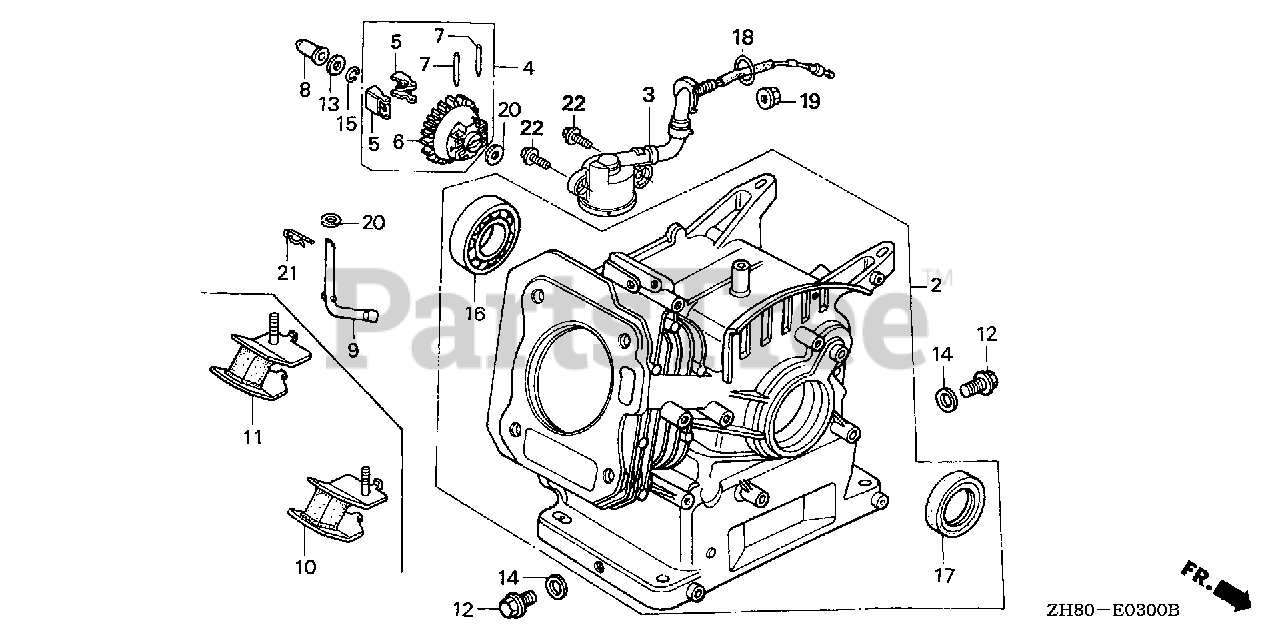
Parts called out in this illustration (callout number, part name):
2	CYLINDER ASSY.
4	GOVERNOR ASSY.
5	WEIGHT, GOVERNOR
6	HOLDER, GOVERNOR WEIGHT
7	PIN, GOVERNOR WEIGHT
8	SLIDER, GOVERNOR
9	SHAFT, GOVERNOR ARM
12	BOLT, DRAIN PLUG
13	WASHER, THRUST (6MM)
14	WASHER, DRAIN PLUG (10.2MM)
15	CLIP, GOVERNOR HOLDER
16	BEARING, RADIAL BALL (6205TMB) (NTN)
17	OIL SEAL (25X41X6)
20	WASHER, PLAIN (6MM)
21	PIN, LOCK (8MM)
